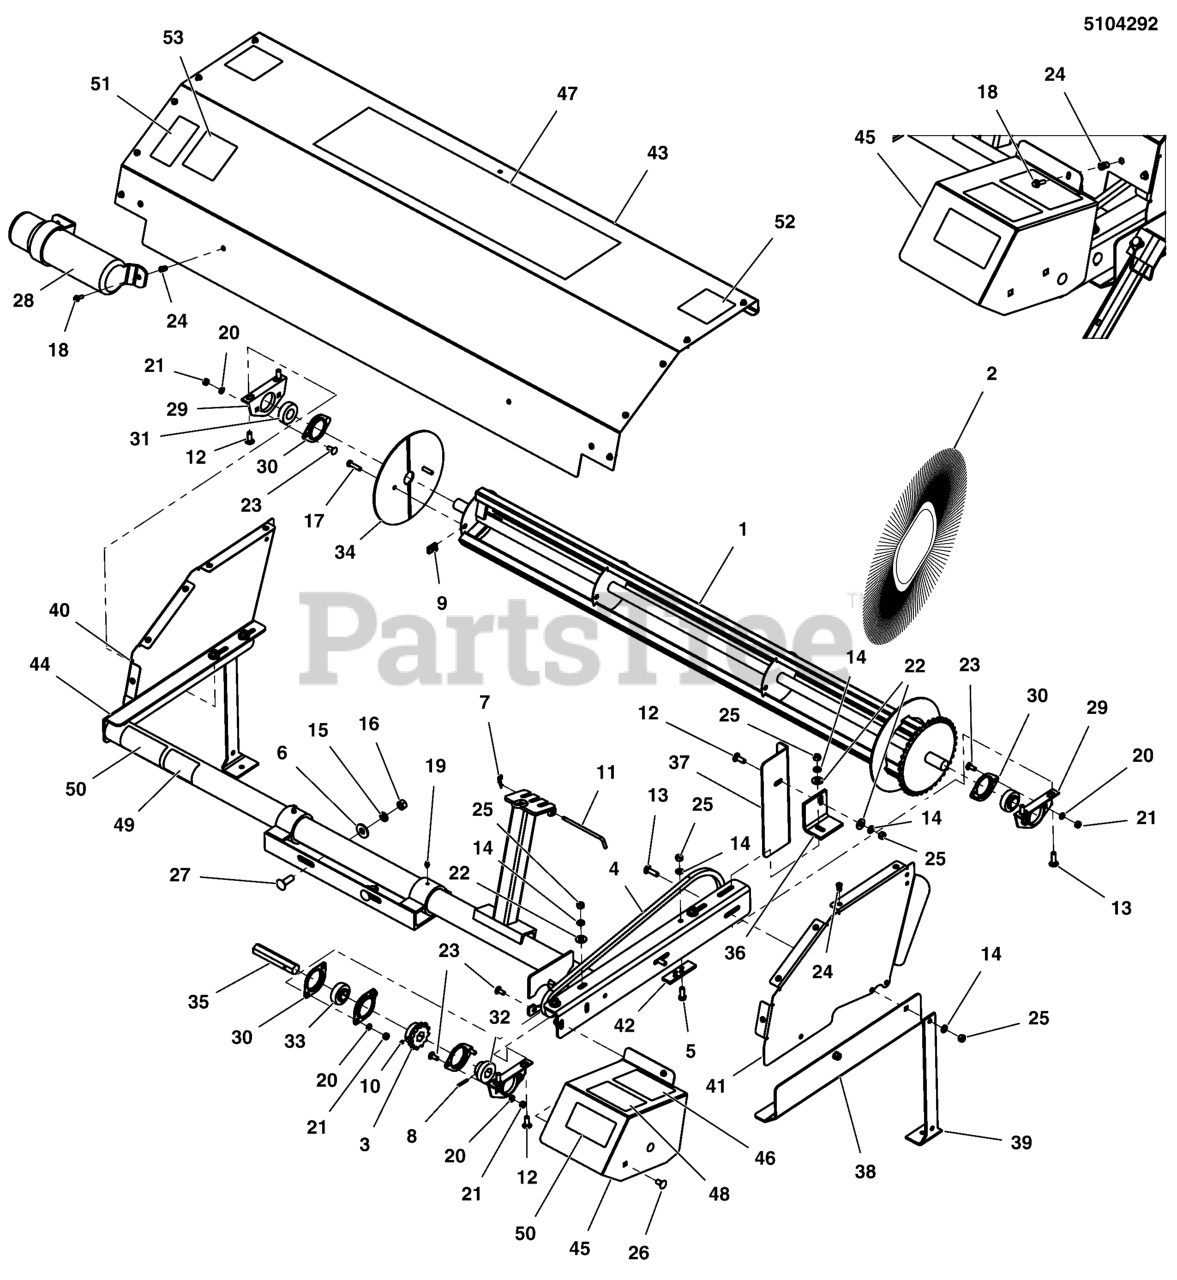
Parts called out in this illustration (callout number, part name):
1	WELD CORE SECT 5 B60 HD
2	SECT 24 P CONV HVY FILL BLACK
3	SPROCKET 50B12 7/8xHEX** THRU HOLE
4	CHAIN #50 88 LINKS W/MST
5	SCREW HHC GR8 3/8-16 X 1 PLD
6	WASHER FL GR8 1/2 PLD
7	CLIP HAIRPIN 16GAx1 3/8 PLD
8	PIN SPRING LOCK GR2 3/16x1 1/4 BLK OXIDE
9	NUT LOCK STAMPED 5/16-18 TIMMERMAN
10	SCREW, SET, GR2, 1/4-28 X 1/4, CUP PT, PLD
11	PIN CHAIN KEEPER 1/4x4 1/2 PLD
12	BOLT, CRG, GR5, 3/8-16 x 1, YLW DI-CR
13	BOLT CRG GR5 3/8-16x1 1/4 PLD
14	WASHER LOCK SPLIT MED 3/8 PLD
15	WASHER LOCK SPLIT MED 1/2 PLD
16	NUT HEX GR8 1/2-13 PLD
17	SCREW HHC GR8 5/16-18x1 1/4 PLD
18	SCREW HFH CL10.9 M6-1x20 PLD
19	FTG ZERK 1/4-28 SELF TAP
20	WASHER LOCK SPLIT MED 5/16 PLD
21	NUT HEX GR8 5/16-18 PLD
22	WASHER FL GR8 3/8 PLD
23	BOLT CRG GR5 5/16-18x 3/4 PLD
24	NUT INSERT HEX M6x1
25	NUT HEX GR8 3/8-16 PLD
26	BOLT CRG GR5 3/8-16x3/4 PLD
27	BOLT CRG GR5 1/2-13x1 1/2 PLD
28	MANUAL HOLDER
29	FLANGE BRG PBS ONLY
30	FLANGE BRG 2 HOLE PLD
31	BEARING 1.00 RD W/COLLAR ONLY
32	BEARING HEX .875 W/HOLE
33	BEARING 7/8 HEX WITHOUT HUB
34	PLATE RETAINER SECT SET C48
35	SHAFT HEX 7/8x5 W/HOLE @ 1
36	PLATE MTG SHIELD BHEAD
37	SHIELD DRV CORE FRT
38	SHIELD BRSH SIDE RT M24
40	SHEET SIDE HOOD LT S26/S30 2004
41	SHEET SIDE HOOD RT S26/S30 2004
42	PLATE ADJ STOP M24
43	SHEET HOOD M24 5 FT
44	WELD FRM BRSH 5FT BRIGGS & STRATTON
45	SHIELD DRIVE REAR M24 BRIGGS & STRATTON
46	LABEL DANGER ROT DRV LINE
47	LABEL LOGO SWPSTR WHITE XL 7.63x32.00
48	LABEL, CAUTION, NO STEP
49	LABEL SERIAL # SWEEPSTER COMPLETE
50	LABEL WARNING CRUSH HAZARD 2.50 x 5.00
51	LABEL WARN MISUSE HAZARD 2.5x4.75
52	LABEL WARNING FLYING OBJ & ENTANGLEMENT 4.0 x 3.75
53	DECAL WARNING HAZARDOUS DUST
